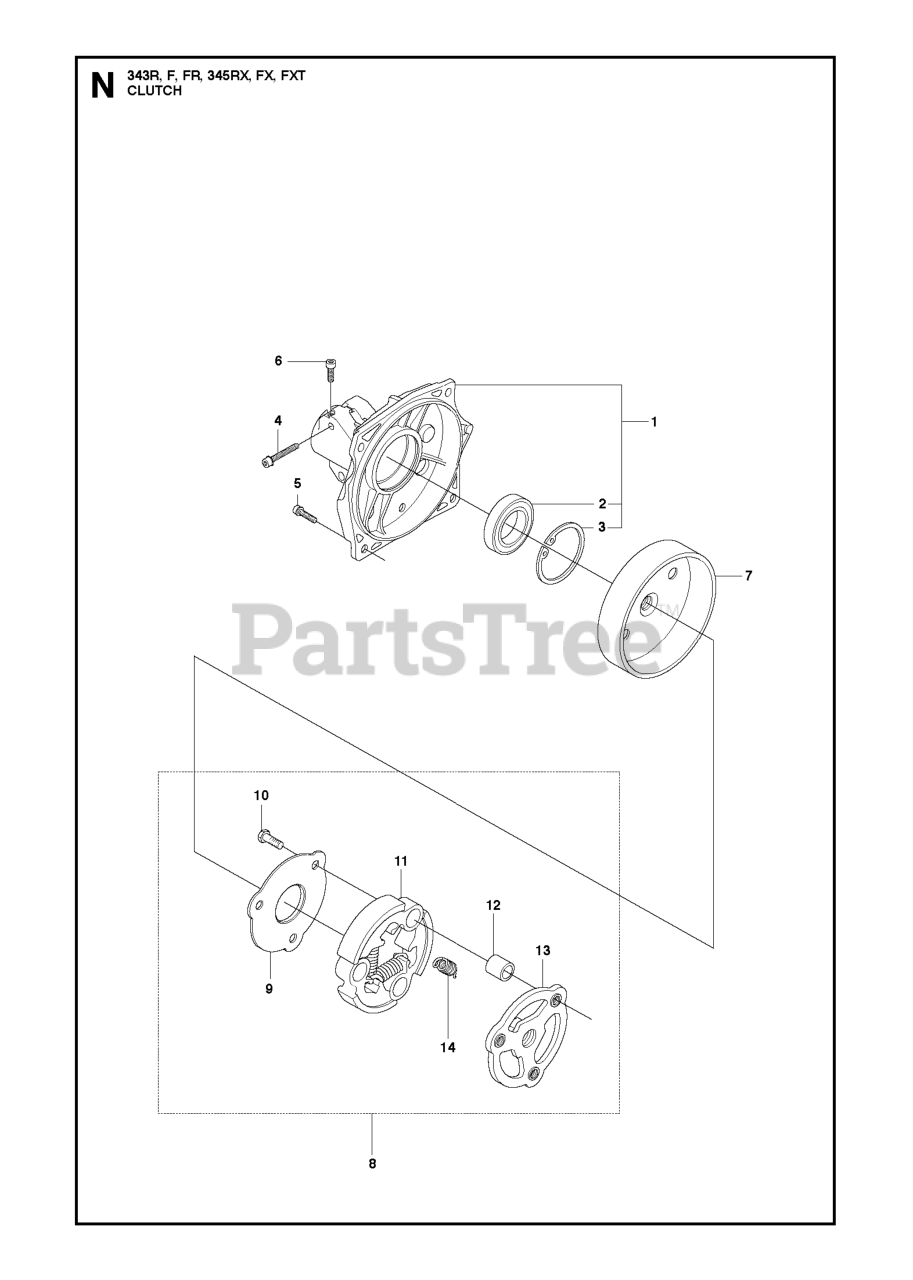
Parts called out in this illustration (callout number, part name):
1	CLUTCH COVER
2	BALL BEARING 6202-2RS1
3	RETAINING RING SGH 35
6	SCREW MC6LS 5X12
7	CLUTCH DRUM ASSM.
8	CLUTCH CPL
10	SCREW
14	CLUTCH SPRING
